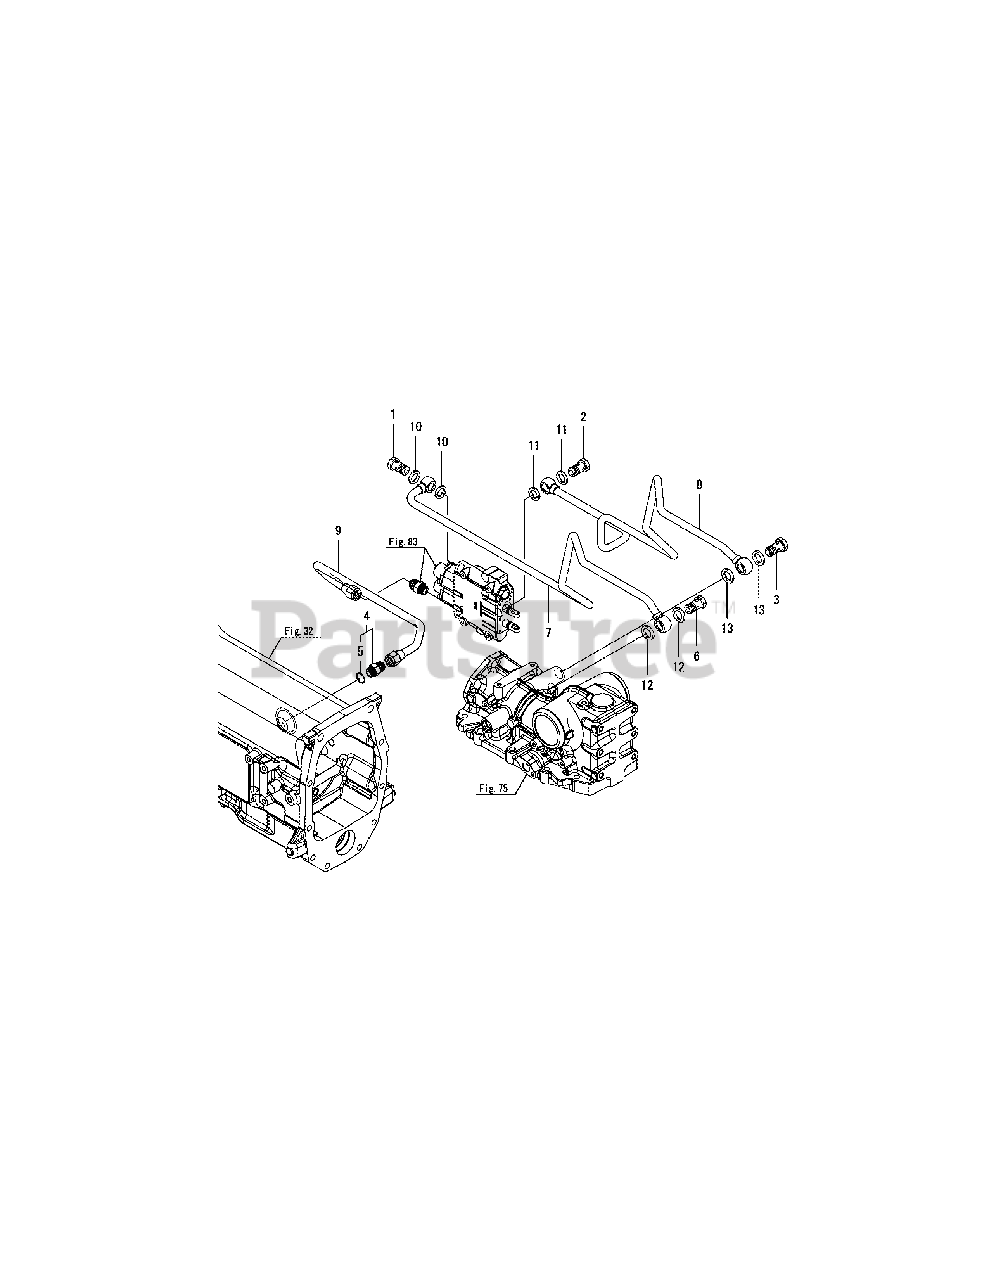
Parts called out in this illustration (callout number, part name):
3	BOLT,JOINT ASSY
4	FITTING/HYD, 3/4-7/8
7	HP PIPE, SCV-P
8	HP PIPE, SCV-C
9	HP PIPE, SCV-T
